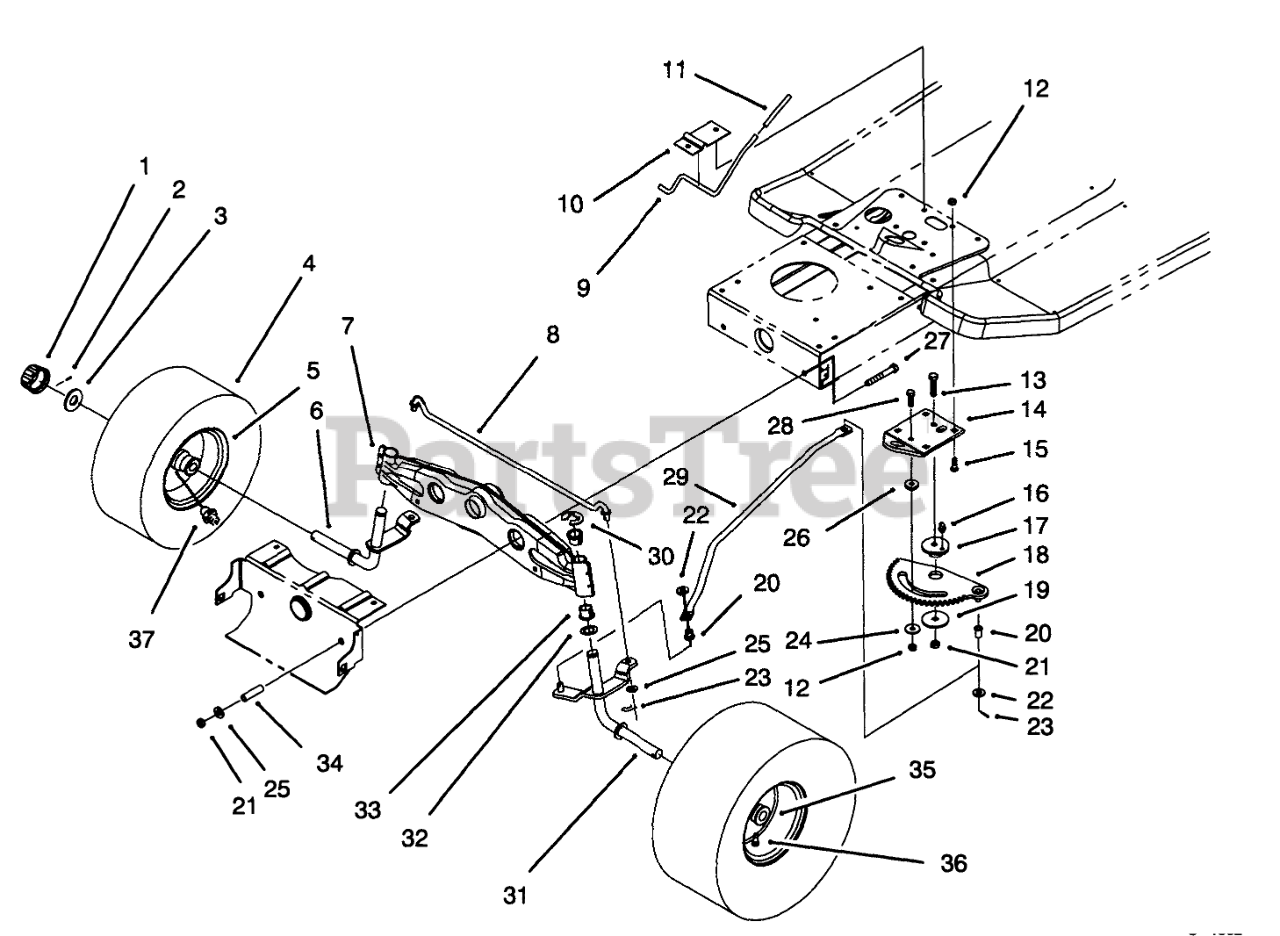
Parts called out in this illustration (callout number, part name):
1	CAP-HUB
2	PIN-COTTER
3	WASHER-PLAIN
4	TIRE 13 X 5.00 X 6
5	RIM ASM
6	Spindle-R.H.
7	Axle-Front
8	TIE ROD-STEERING
9	ROD-BRAKE, PARKING
10	Bracket-Parking Brake
11	GRIP-BRAKE, PARKING
12	NUT-LOCK, NI
13	SCREW-CARR
14	Bracket-Steering Rack
15	BOLT-CARR
16	FITTING-GREASE
17	BUSHING-ECCENTRIC
18	RACK-STEERING
19	WASHER-BEARING
20	BUSHING-FLANGED, NYLON
21	NUT-LOCK, NI
22	WASHER-FLAT
23	PIN-COTTER
24	WASHER-PIVOT
25	WASHER-FLAT
26	SPACER-RACK, STEERING
27	SCREW-HH
28	SCREW-CARR
29	LINK-DRAG
30	E-RING
31	Spindle-L.H.
32	WASHER-THRUST
33	BUSHING
34	SPACER
35	BEARING-WHEEL
36	STEM-VALVE
37	FITTING-GREASE
